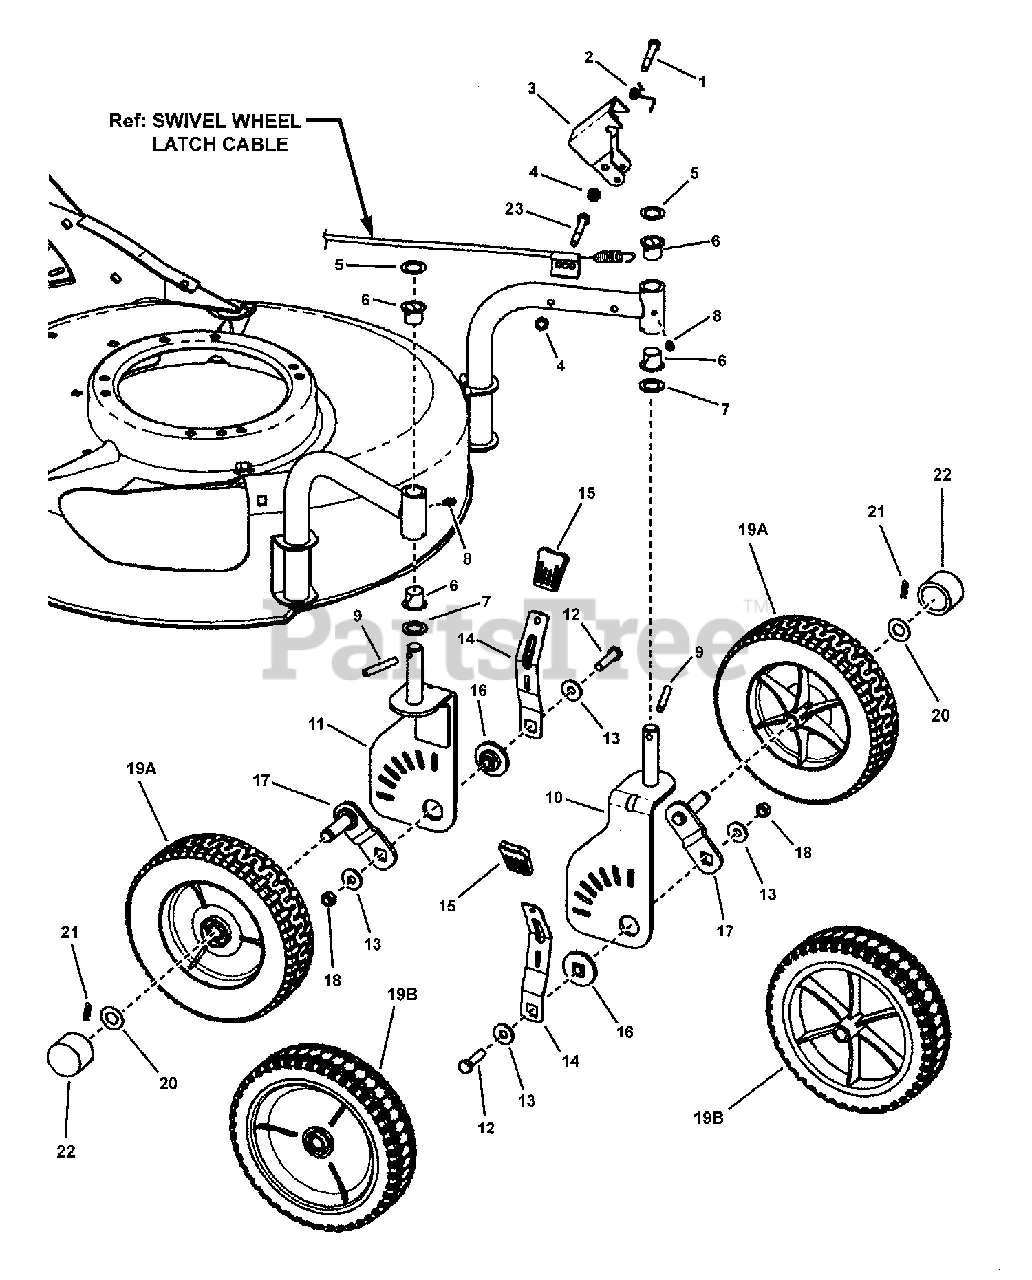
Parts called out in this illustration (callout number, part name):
1	SCREW, 1/4-20 x 2-1/4" Hex Head Cap, GR 5
2	SPRING, Torsion
3	BRACKET Swivel Wheel Lock, Red
4	NUT, 1/4-20 Hex Center Lock
5	WASHER, .64 x .99 x .025 Flat
6	BUSHING, 5/8" Nyliner
7	WASHER, .64 x .99 x .075 Flat
8	LUBE FITTING, 3/16"
9	ROLL PIN, 1/4 x 1-3/4"
10	WELDMENT, Swivel Wheel Brkt. LH (Red)
11	WELDMENT, Swivel Wheel Brkt. RH (Red)
12	SCREW, 5/16-18 X 1-1/4" Hex Head Cap, GR 5
13	WASHER, .875 x .327 x .090 Flat
14	LEVER, Height Adjust, Swivel Wheel
15	GRIP, Height Latch - Black (1.3" Wide)
16	SPACER, Swivel Wheel Pivot
17	ASSEMBLY, Axle Arm/Stud
18	NUT, 5/16-18 Hex Center Lock
19A	WHEEL, Front 8 x 2", LS Tread, 1-3/8" Hub Length
19B	WHEEL, Front 8 x 2", Dbl Bar II Tread, 1-3/8" Hub
20	WASHER, Shim, .875 x .531 x .060
21	COTTER, Hairpin
22	HUB CAP, 1-3/8" Diameter (black)
23	SCREW, 1/4-20 x 2" Hex Head Cap, GR 5
